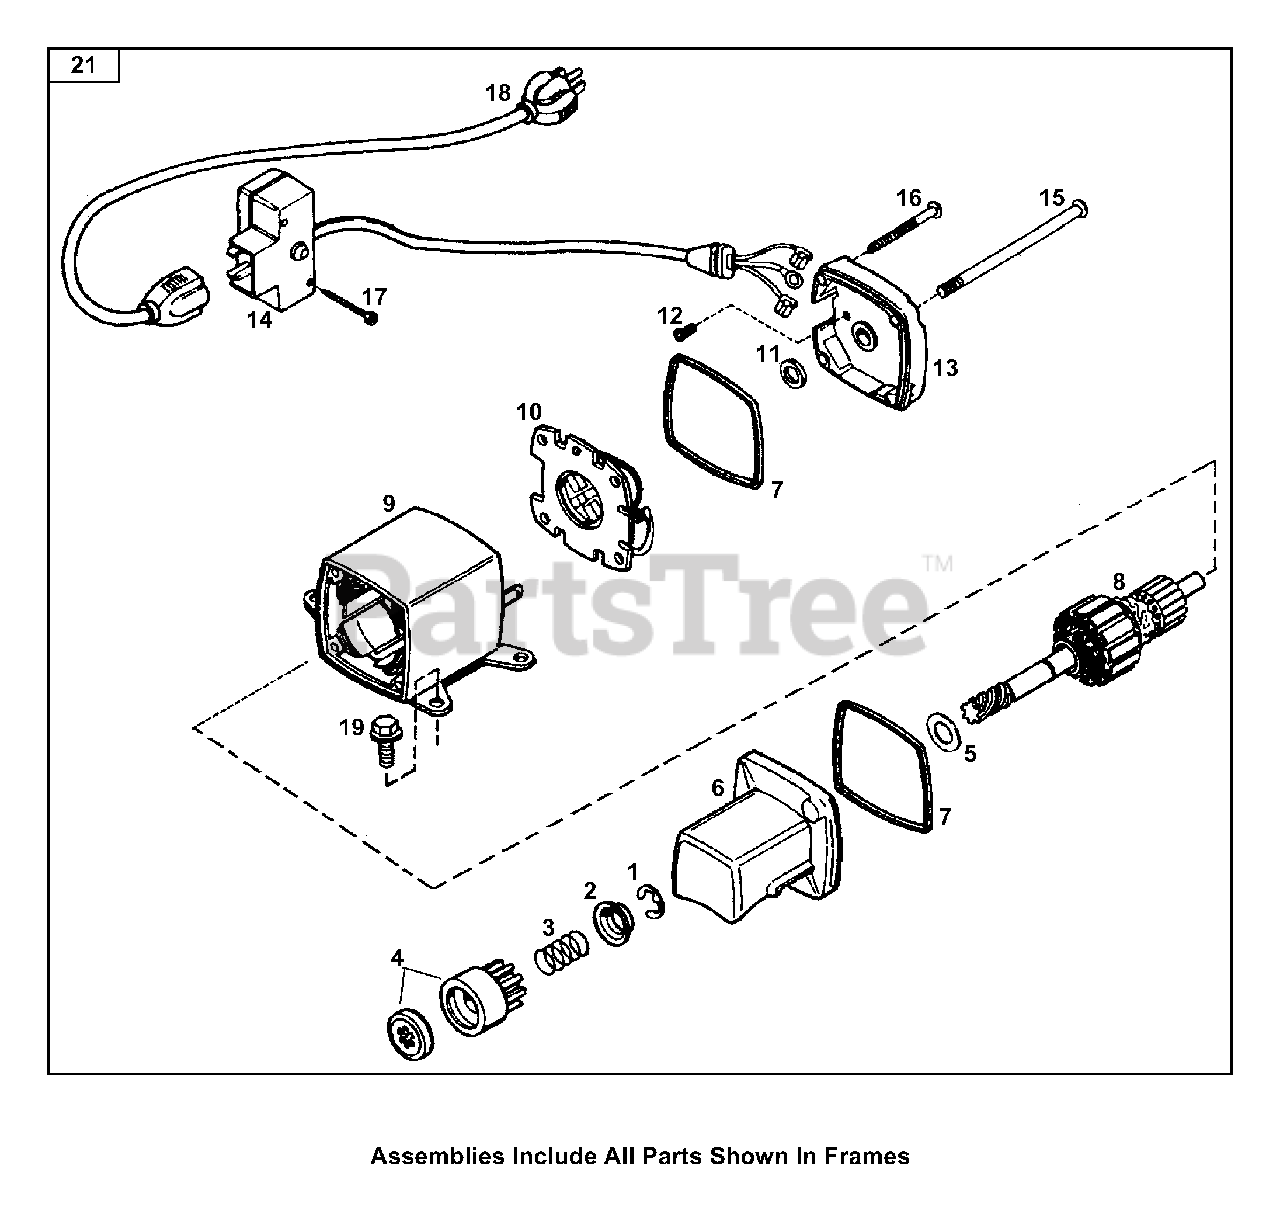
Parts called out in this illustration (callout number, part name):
1	Retainer Ring
2	Spring Retainer
3	Anti-Drift Spring
4	Nut & Gear
5	Thrust Washer
6	Drive End Cap Ass'y
9	Housing Ass'y
10	Brush & Spring Card Ass'y
11	Thrust Washer
12	Ground Screw
13	Commutator End Cap Ass'y
14	Switch Box Ass'y
15	Case Bolt
16	Grounding Screw
17	Screw, 6-32 x 2-1/2"
18	Extension Cord
19	Screw, Torx T-30, 1/4-20 x 23/32"
21	Electric Starter (110 Volt)
